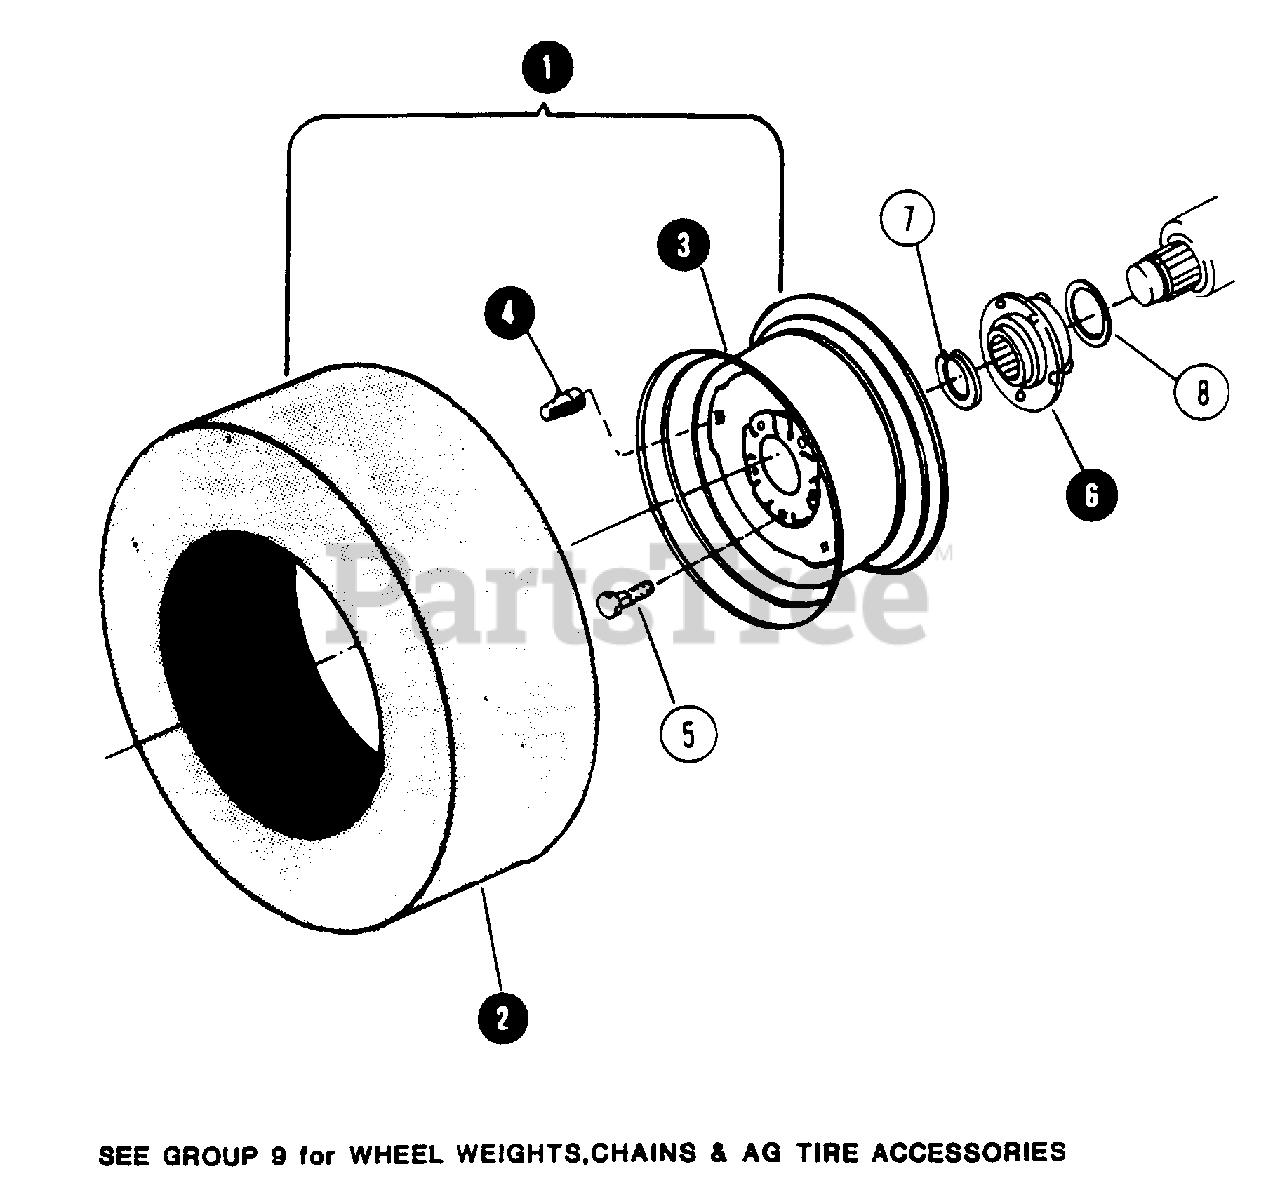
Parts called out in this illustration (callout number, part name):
1	WHEEL ASSEMBLY
2	TIRE, 23 x 10.50 x 12
4	VALVE, AIR
5	BOLT, REAR WHEEL TO HUB
6	HUB, REAR WHEEL
7	RING, RETAINING - HUB TO TRANSAXLE
8	SHIM, .005" - HUB TO TRANSAXLE
